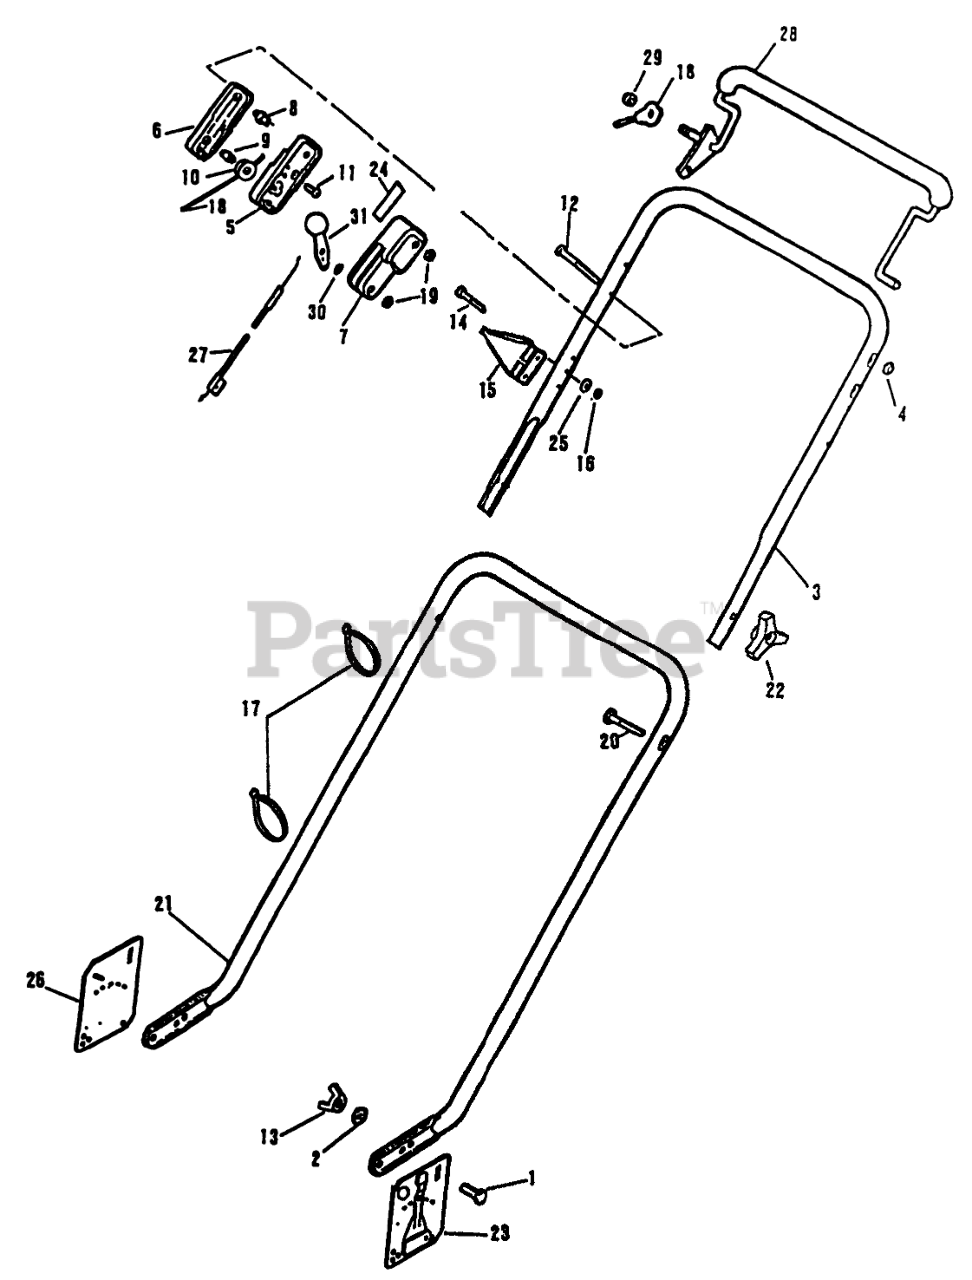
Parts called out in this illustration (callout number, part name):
1	Bolt
2	WASHER LOCK B'GER
3	Handle-Top
4	NUT-PUSH
5	CENTER CONTROL CASE
6	OUTER CONTROL CASE
7	INNER CONTROL CASE
8	COLUMN
9	PIN SKF
10	PULLEY PL
11	SCREW
12	SCREW
13	NUT WING
14	SCREW
15	GUIDE - ROPE
16	LOCKNUT E
17	TIE-CABLE
18	CONTROL CABLE
19	NUT C/LOCK E
20	Screw
21	Handle-Lower
22	Knob
23	ASM-Bracket & Pin
24	DECAL-THROT CONTRL
25	WASHER
26	ASM-Bracket & Pin
27	CABLE TH'TTLE WES
28	CONTROL LEVER ARG
29	NUT ACORN
30	WASHER-SPRING
31	LEVER&KNOB AY WES
